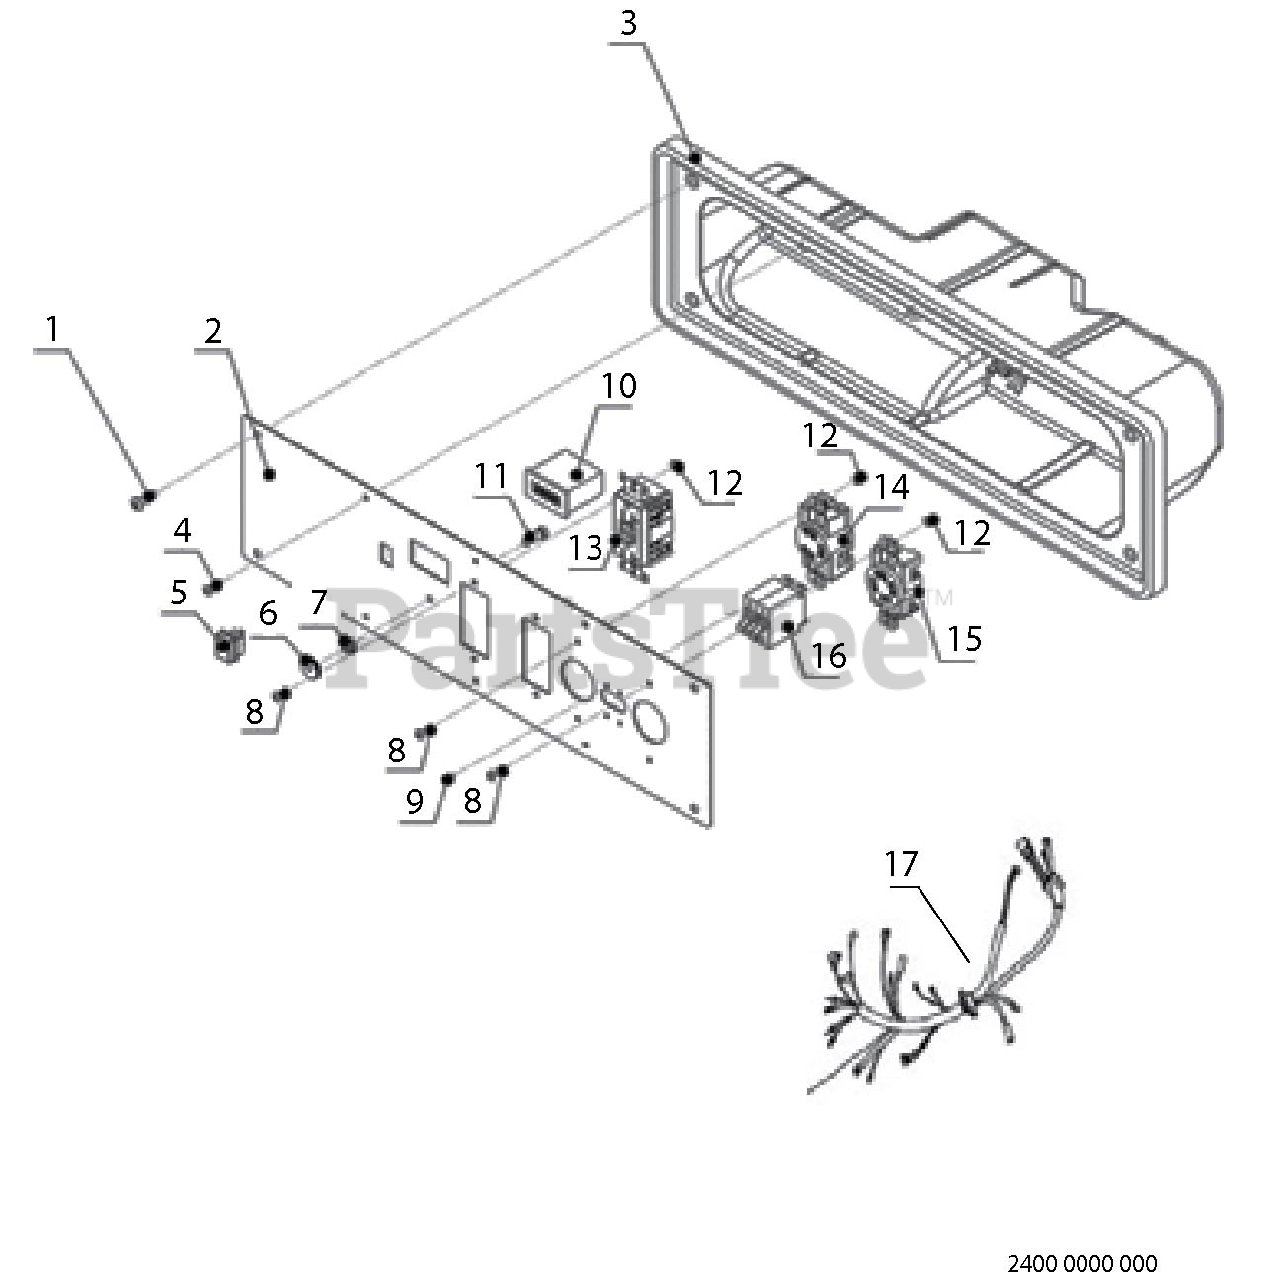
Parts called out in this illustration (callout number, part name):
1	BOLT
2	CONTROL PANEL CP
3	CONTROL BOX
7	NUT
8	BOLT
11	BOLT
12	NUT FLANGE
13	AC CONCENT,GFCI
16	BREAKER
17	WIRE HARNESS
